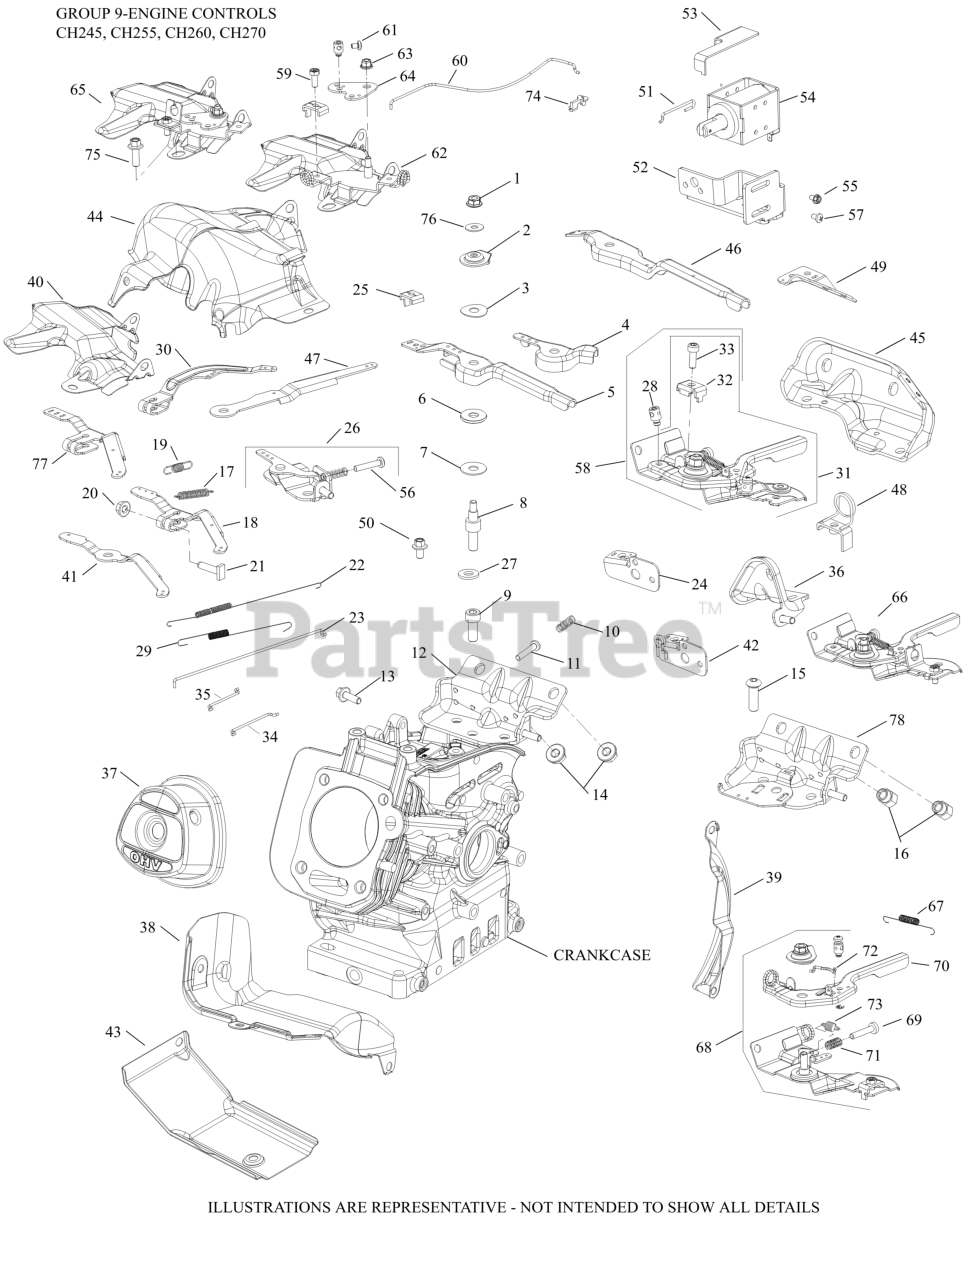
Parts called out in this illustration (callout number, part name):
1	NUT, HEX FLANGE LOCK (M6)
2	WASHER, CONTROL LEVER
3	WASHER, SPRING
5	LEVER, CONTROL (THROTTLE)
6	WASHER, NYLON CONTROL LEVER
7	WASHER, FLAT
8	STUD, CONTROL LEVER
9	SCREW, HEX SOCKET HD CAP
10	SPRING, COMPRESSION
11	SCREW, SPEED ADJUSTING
12	BRACKET, FUEL AND CONTROLS
14	NUT, FLG M8X1.25
18	KIT, GOVERNOR LEVER
19	SPRING, GOVERNOR
20	NUT, HEX FLANGE (M6) - USE 14 100 16-S
21	SCREW, RECTANGLE HEAD (M6)
22	SPRING, LINKAGE
23	LINKAGE, GOVERNOR
24	BRACKET, CABLE CLAMP
25	CLAMP, CABLE
28	KIT, CABLE CLAMP
